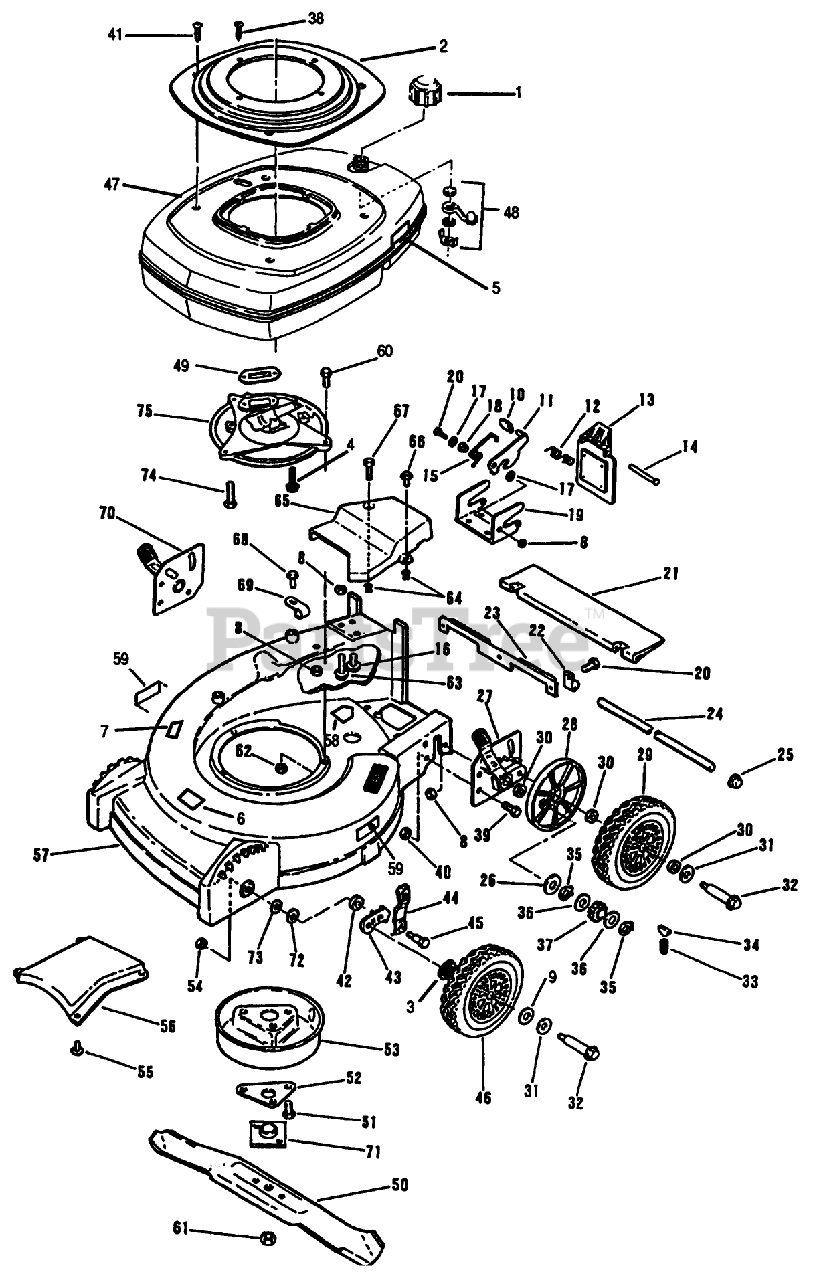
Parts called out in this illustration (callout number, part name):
1	FUEL CAP & INSERT
3	WASHER WROUGHT
4	SCREW-SEMS F
8	LOCKNUT E
9	LOCKNUT
10	KNOB (S&R)
12	SPRING ASOC
14	ROD (RB&W)
15	SPRING
16	SCREW HEX WASHER
21	T/SHIELD SM&P
26	THRUST WASHER
27	HEIGHT ADJ. AY.
30	WASHER
31	SPACER
32	BOLT WHEEL
33	SPRING
34	KEY
35	RET RING
36	SPACER/GR ALGHNY
37	PINION BROCKWAY
38	SCREW SEMS SM
39	SCREW - HEX
40	NUT-LOCK F
41	SCREW - SELF TAPPING
42	WASHER
44	SPRING ARM ASM
45	BOLT
46	WHEEL&TIRE 8" TRI
48	SHUT-OFF VALVE S
50	20" Blade
51	SCREW
52	SUPPORT F
53	MUFFLER COVER F
54	LOCKNUT
56	BAFFLE CHUTE PL
60	SCREW-HH
61	NUT-BLADE
62	NUT-LOCK F
63	SCREW
66	SCREW
68	SCREW LAWRENCE
70	HT. ADJ. AY.
71	PLATE AND COLLAR ASM
72	WASHER
73	WASHER
74	SCREW V
75	PLATE F
